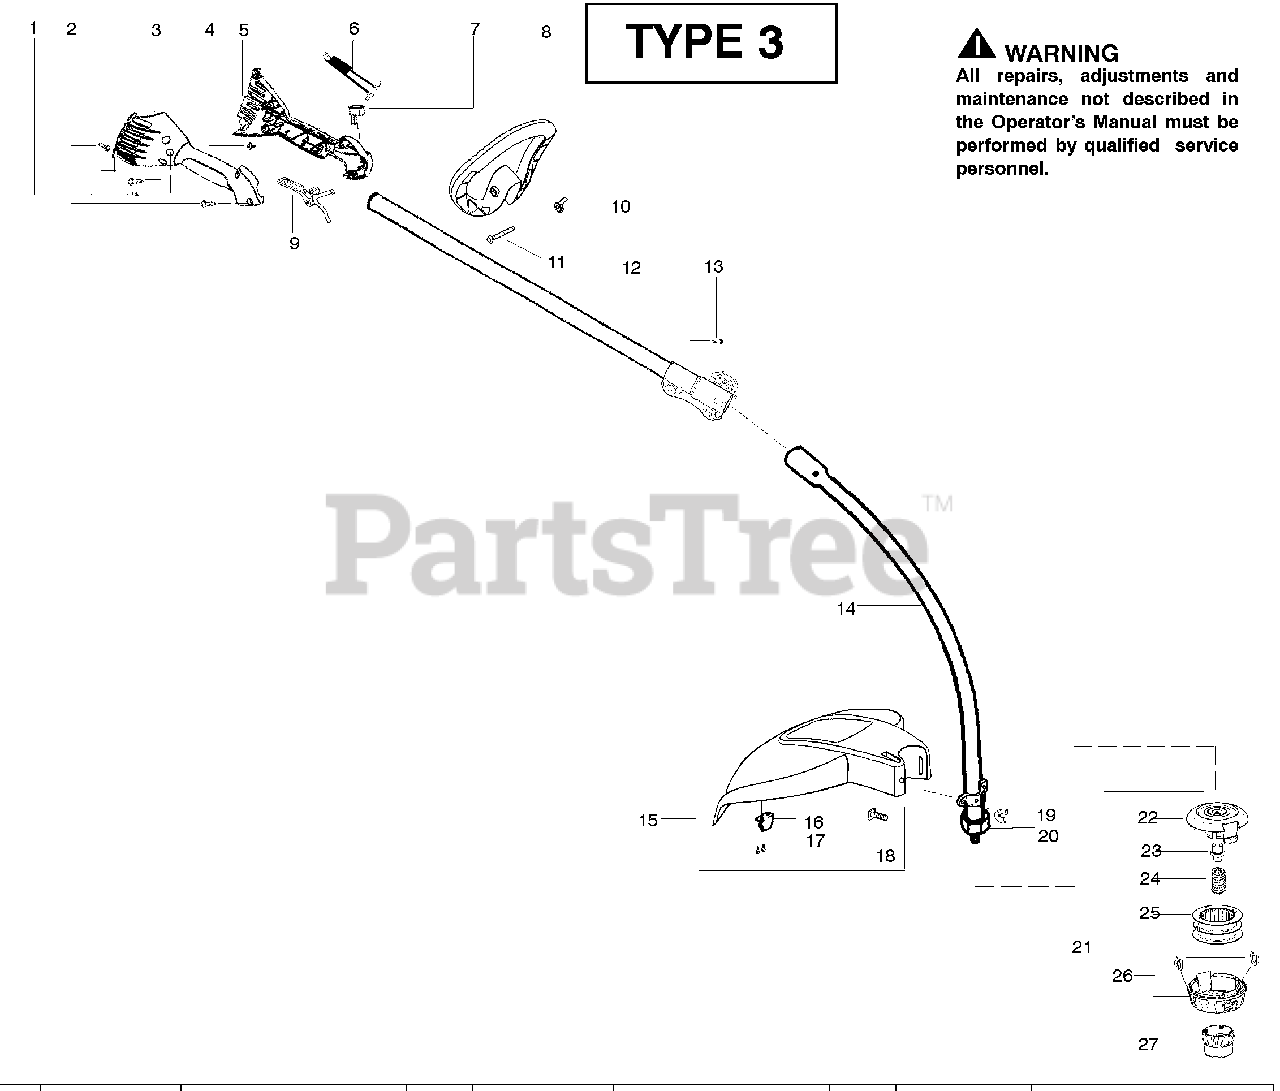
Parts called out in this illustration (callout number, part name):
1	Screw-alignment
3	Hsg.-Throttle right
4	Screw-Cable Retention
5	Hsg.-Left throttle
8	Assy-Assist Handle
9	Trigger-Throttle
10	Wingnut
12	Kit-Upper Shaft
14	Kit-Lower Shaft
15	Kit-Shield Assy.
19	Wingnut
21	Accy-TNG7 Head
24	Spring
25	Accy-Wound Spool
26	Kit-Cover and Eyelet
27	Knob
